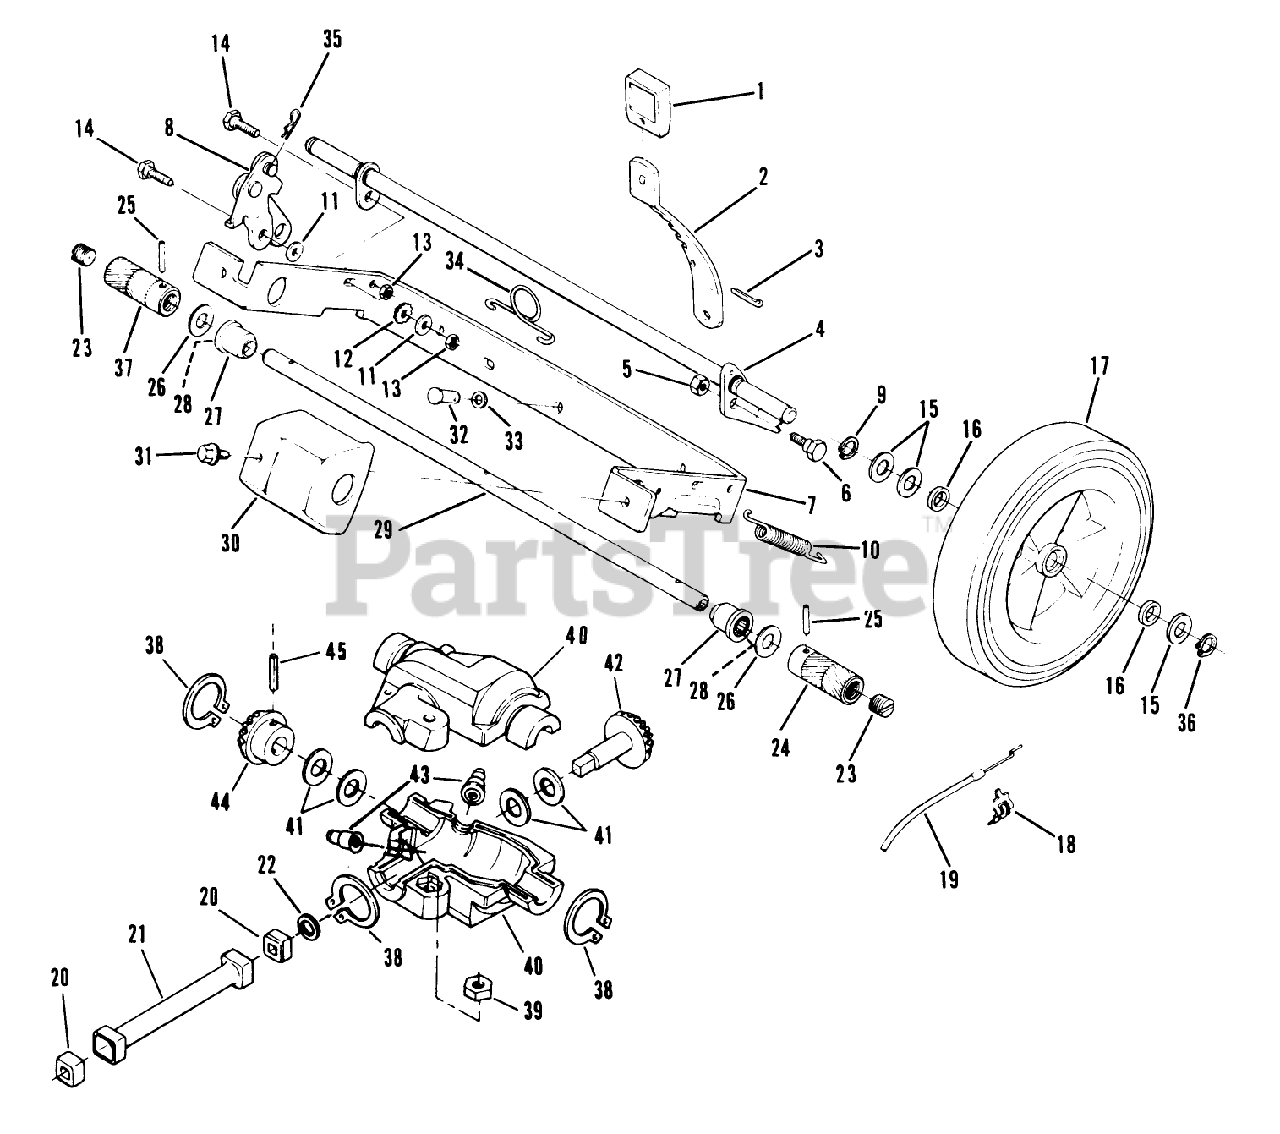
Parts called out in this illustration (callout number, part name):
1	Knob-Rear Ht. Adj Lever
2	LEVER
5	LOCKNUT E
6	BOLT RB&W
7	BRK-21" AXLE
9	RET RING
10	SPRING
11	WASHER S
13	STOP NUT
14	BOLT RB&W
15	SPACER
16	WASHER
20	BUSHING
22	O-RING
23	GREASE PLUG
24	ROLLER-LEFT
25	PIN
28	BEARING AY F
29	DRIVE SHFT TAG AY
30	GUARD
32	PIN
33	WASHER SPRING LAR
34	SPRING N.A.S
36	RET RING
37	DRIVE ROLLER
39	LOCKNUT E
41	THRUST WASHER
42	GEAR BEST
43	ZERK FITTING
44	GEAR ADVANCE
45	ROLL PIN
